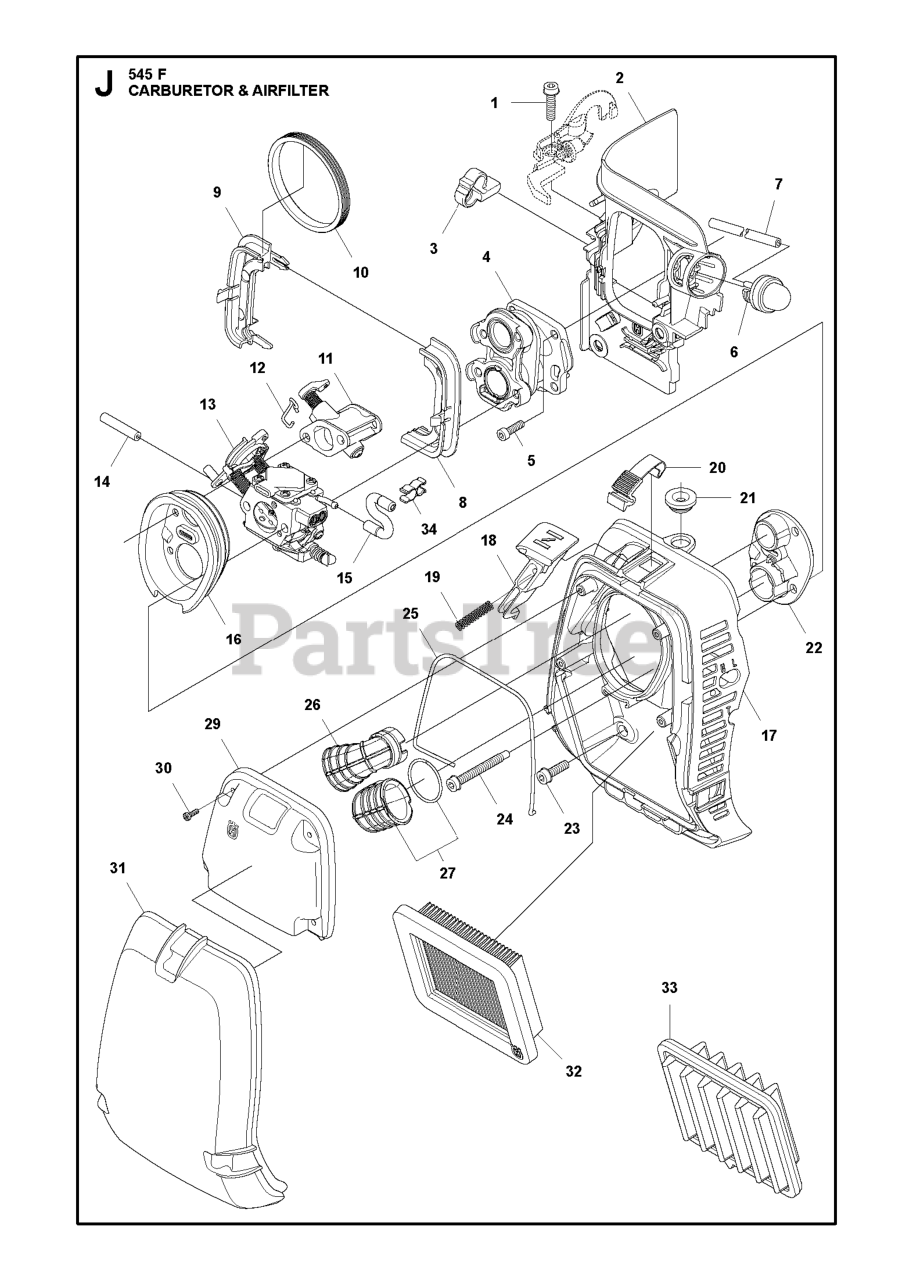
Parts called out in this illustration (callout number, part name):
2	INSULATION WALL
4	INLET PIPE
6	AIR PURGE BUBBLE
10	SEALING RING
13	CARBURETOR
14	FUEL HOSE STRAIGHT 38
17	FILTER HOLDER ASSY
18	CHOKE CONTROL
22	COVER PLATE
23	SCREW IHSCFM
26	INLET PIPE AIR HEAD
29	COVER LID ASSY
31	FILTER COVER
32	FILTER AIR FILTER PAPER
33	Filters
